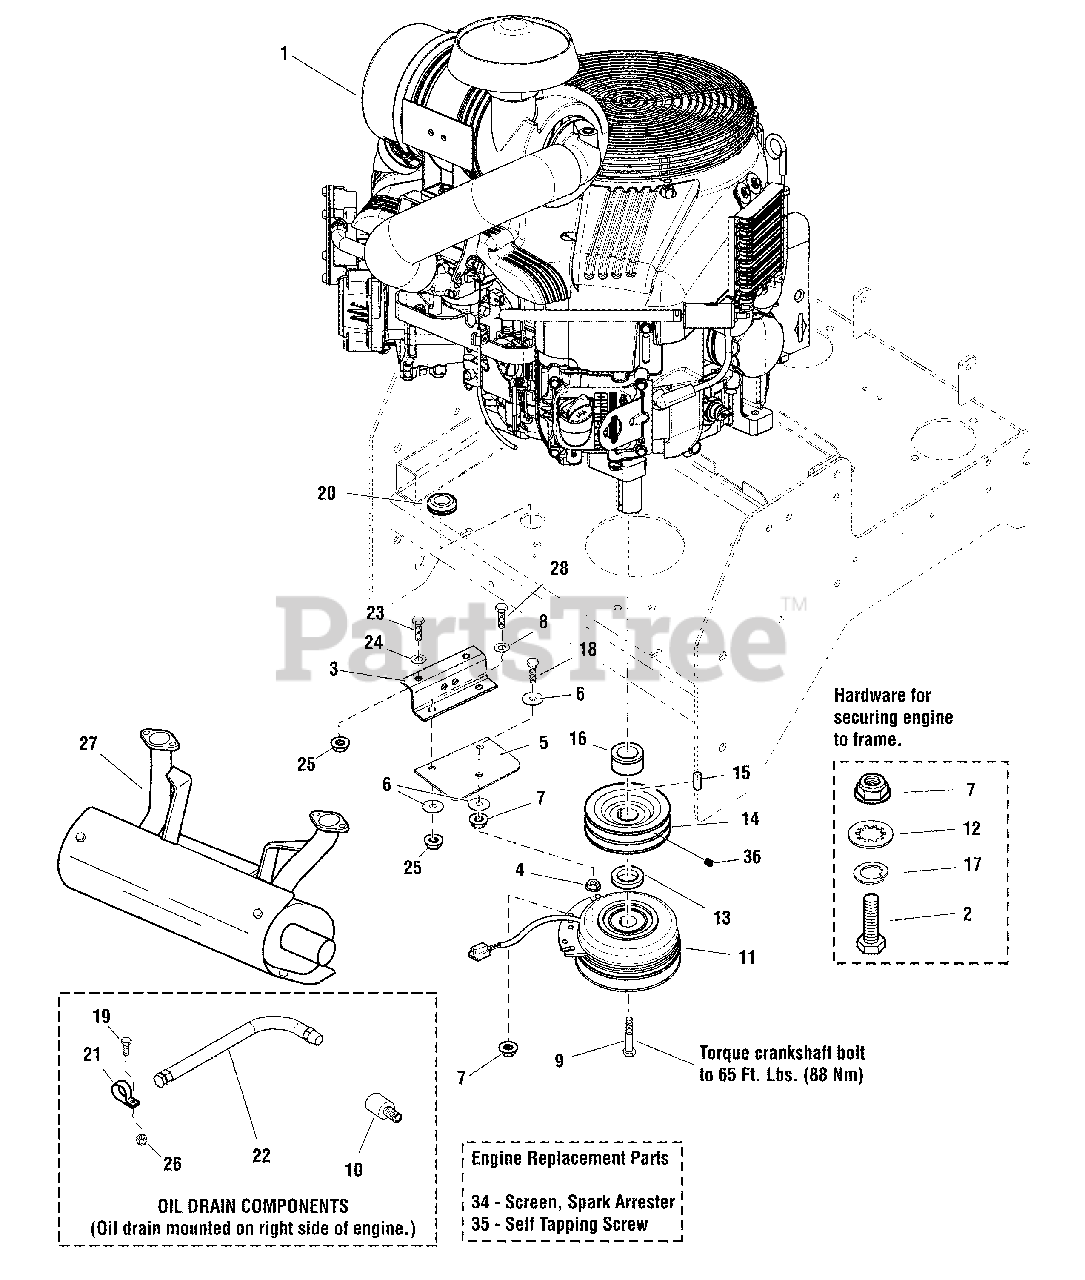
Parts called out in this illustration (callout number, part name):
1	* ENGINE, BRIGGS AND STRATTON
2	BOLT, 5/16-18 X 1-3/4" GD5 YZ
3	ANCHOR, CLUTCH - BLK
4	NUT, 5/16-18 HEX SERRATED FLANGE (LARGE)
5	CLUTCH ANCHOR PAD
6	WASHER, .34 X 1.25 X 10 GA
7	NUT, 5/16-18 HEX NYLOCK FLANGE NUT
8	WASHER, 5/16" SAE
9	BOLT, CRANKSHAFT,7/16-20X2-1/2, GD8
10	METRIC ADAPTER, M14-1.5" TO 3/8 NPTF
11	CLUTCH WARNER 200 FT-LB 1.13 X 6.323
12	WASHER, 5/16" Internal Tooth Lock
13	SPACER, 1.13 X 1.75 X .50
14	PULLEY, CRANKSHAFT, 1.126 ID X 4.75 OD
15	KEY, 1/4" SQ. X 1.00"
16	SPACER, 1.13 X 1.75 X 1.09, PM
17	WASHER, 5/16 LOCK YZ
18	BOLT, 5/16-18 X 3", FLT
19	BOLT, 1/4-20 X 1" GD5 CZ
20	GROMMET, 7/8"
21	CLAMP, VINYL INSULATED, 1.00
22	HOSE, OIL DRAIN
23	BOLT, 3/8-16 X 1" GD5 YZ
24	WASHER, 3/8 SAE
25	NUT, 3/8 - 16 HEX NYLOCK FLANGE
26	NUT, 1/4-20, GR5 Flanged Nylock, Zinc/Clear
27	Muffler
28	BOLT, 5/16-18 X 1" GRD5 YZ
36	SET SCREW, 5/16-18 X 3/8, KNURL, W/PATCH
